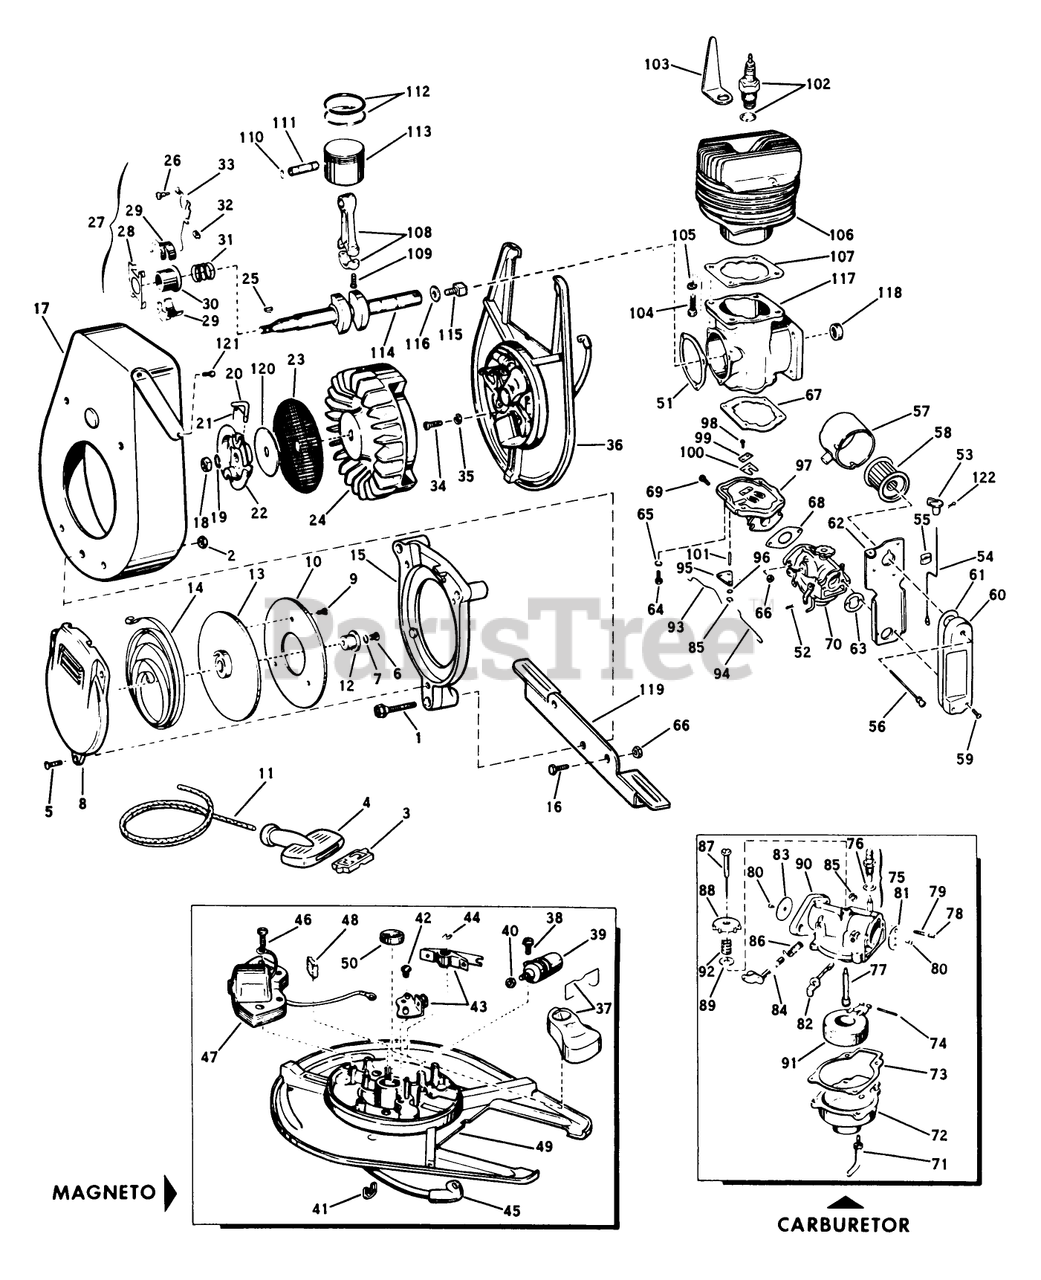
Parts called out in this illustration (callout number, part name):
10	Plate-Pulley
11	Rope-Starter
14	RECOIL SPRING
16	SCREW S
20	PIN - STARTER
30	COLLAR S
31	Spring-Governor
32	WEAR BLOCK S
33	GOVERNER LEVER AY
43	BREAKER AY. S
51	GASKET S
52	Cotter Pin
53	KNOB, CHOKE BAR
54	Choke Rod
55	Spring Clip
56	Screw-Thumb
59	Screw-Sems
60	Chamber-Intake
61	Gasket-Intake Chamber
62	Plate-Filter Attachment
64	SCREW S
67	Gasket-Reed Plate to Crankcase
68	GASKET S
69	SCREW S
71	Screw-Float Bowl to Carb.
80	Screw-Choke Disc
86	Spring-Throttle Shaft
87	NEEDLE AY. S
90	Carburetor Body
92	Spring-Ndl. Adj.
93	Rod-Governor
94	Link-Throttle
95	Bell Crank
99	PLATE-BACKUP, REED
101	Roll Pin
102	Spark Plug
106	Cylinder Sleeve Assembly
107	Gasket-Cylinder to Crankcase
109	Screw-Connecting Rod
112	Ring-Piston
114	Crankshaft
115	Screw-Square Head
116	WASHER, LOCK
119	Bracket-Wheel Scraper
121	SCREW S
122	Cotter Pin
